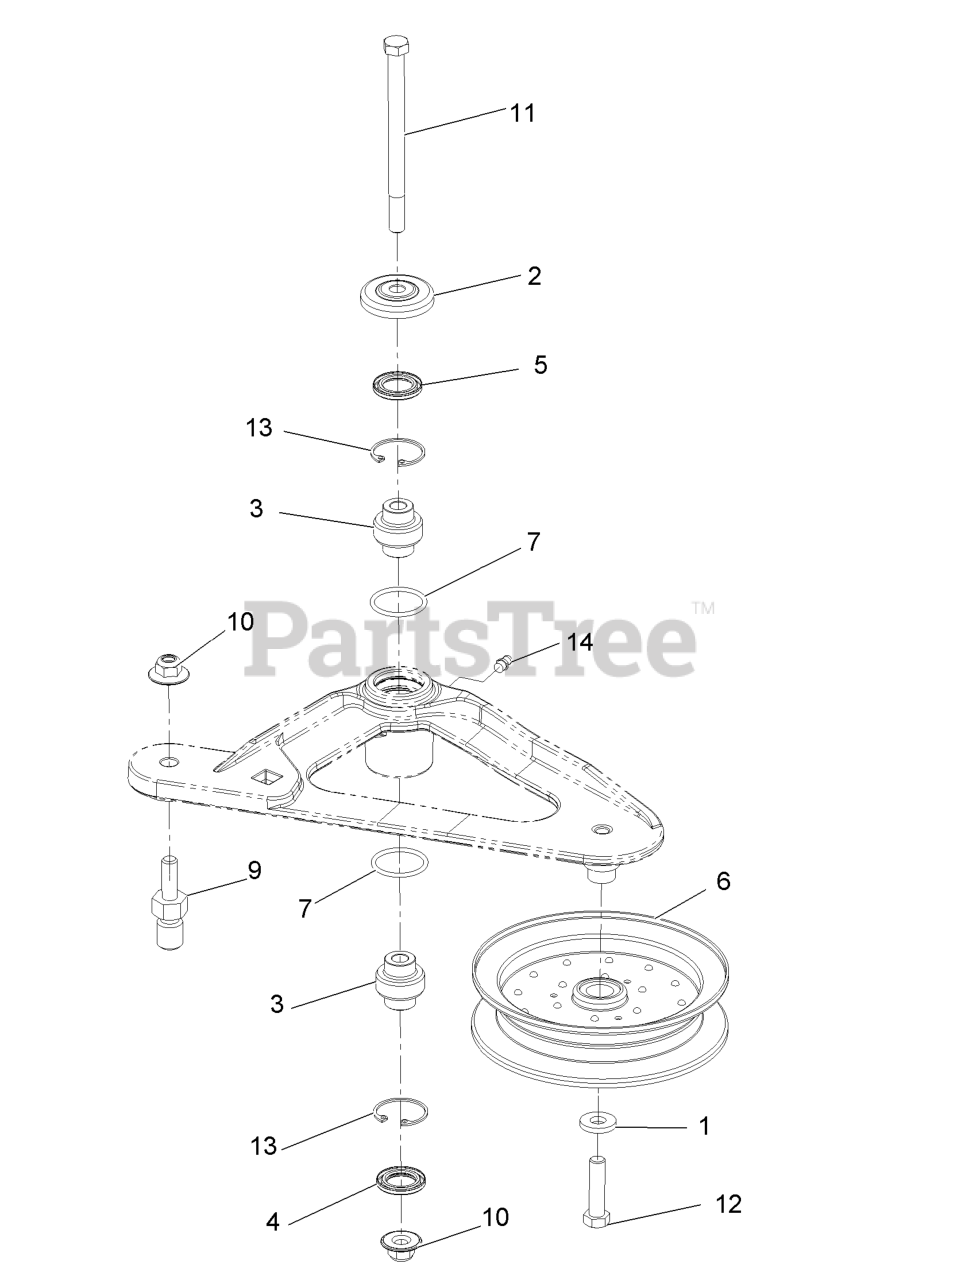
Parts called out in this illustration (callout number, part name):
2	GUARD-TOP
3	BEARING-SPHERICAL
4	SEAL-LIP, DOUBLE
5	SEAL-LIP, SINGLE
10	Nut-Nyloc 3/8-16 Flg
11	SCREW-SHOULDER, HH
12	SCREW-HH
13	RING-SNAP
14	FITTING-GREASE
